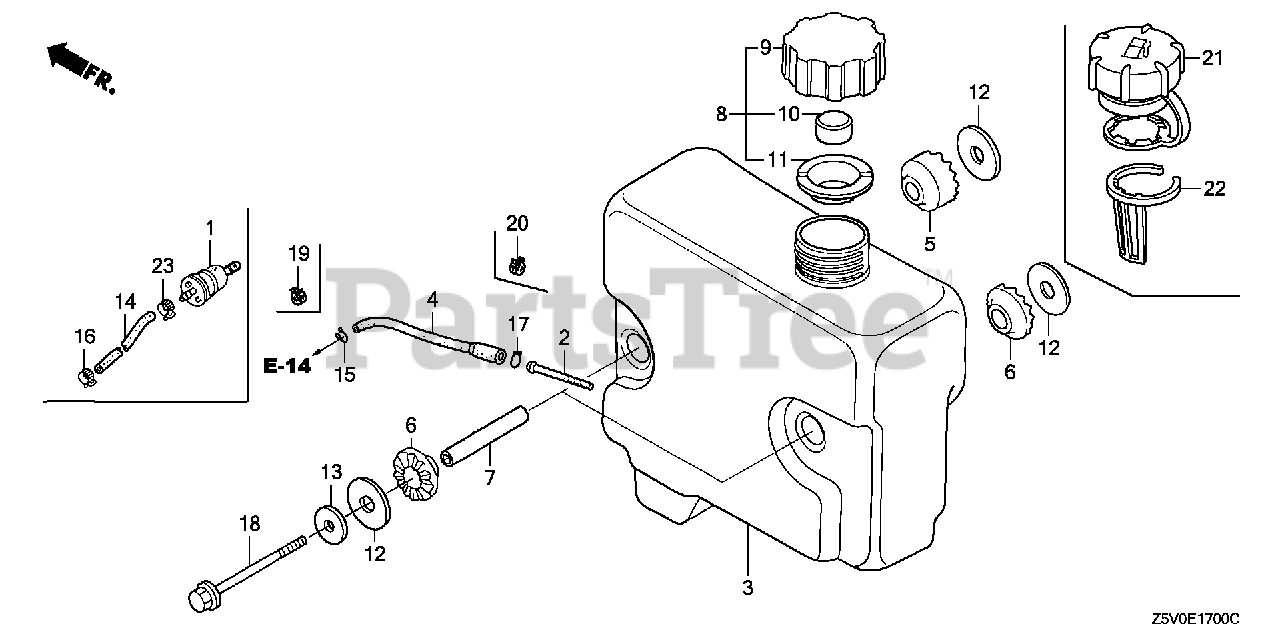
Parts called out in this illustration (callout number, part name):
2	FILTER, FUEL
3	TANK, FUEL
4	TUBE, FUEL
4	TUBE, FUEL (FKM)
5	RUBBER B, TANK MOUNTING
6	RUBBER B, TANK MOUNTING
7	COLLAR, TANK SETTING
8	CAP ASSY., FUEL TANK
9	BODY, FUEL CAP
10	SPONGE, FUEL CAP BREATHER
11	GASKET, FUEL CAP
12	WASHER, TANK MOUNTING
13	WASHER, PLAIN (8MM)
15	CLIP, TUBE (B8)
17	CLIP, TUBE (C11)
18	BOLT, FLANGE (8X95)
19	CLAMP, TUBE (D8)
20	CLAMP, TUBE (D10.5)
21	CAP ASSY., FUEL TANK
22	GAUGE, FUEL LEVEL
